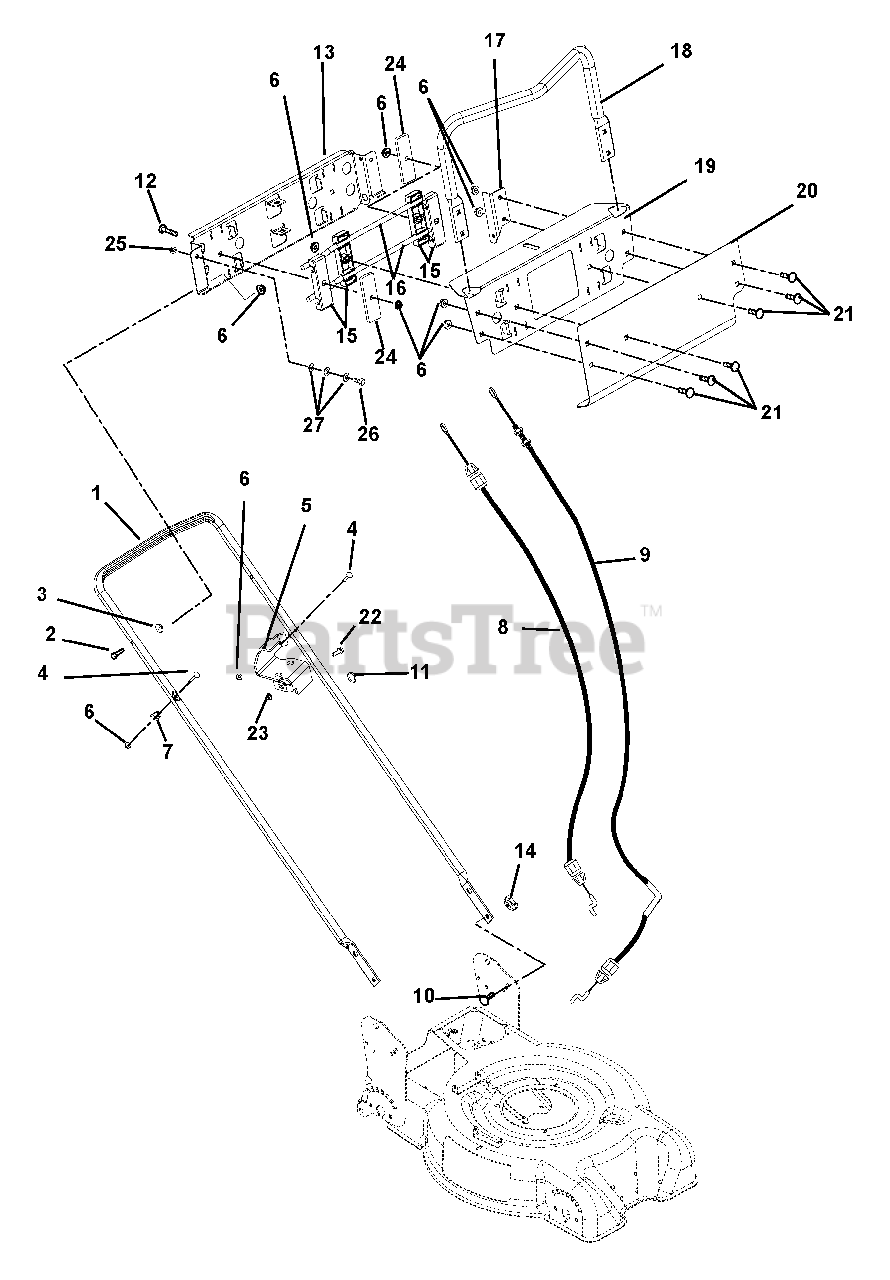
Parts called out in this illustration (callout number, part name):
1	Handlebar
2	Bolt, Hex .25-20 x 1.75 Grade 5
3	Bushing, Flange .265 x .437 x .250 x .750
4	Bolt, Round Head Square Neck .25-20 x 1.25
5	Anchor, Cable Thumb Adjustment
6	Nut, Locking-Top-Flange .25-20
7	Guide, Pullcord
8	Cable, Operator Presence
9	Cable, Traction Thumb Adjustment
10	Bolt, Round Head Square Short Neck .31-18 x .75 Grade 5
11	Clip, Conduit
12	Bolt, Round Head Square Neck .25-20 x 1.00 Grade 5
13	Plate, Hinge
14	Knob, Nyloc Clamping .312-18
15	Clamp, 4-Bar
16	Rod, 4-Bar
17	Bracket, Cable Anchor
18	Bail, .750 Tube
19	Cover, Operator Presence Control
20	Cover, Sheetmetal
21	Bolt, Round Head Square Neck .25-20 x 1.00 Grade 5
22	Bolt, Hex .25-20 x 1.25 Grade 5
23	Nut, Locking-Top-Flange .25-20
24	Plate, Stiffening
25	Nut, Locking, Nylon .250-20
26	Bolt, Hex .25-20 x .50 Grade 5
27	Washer, Flat Steel .25 x .562 x .049
